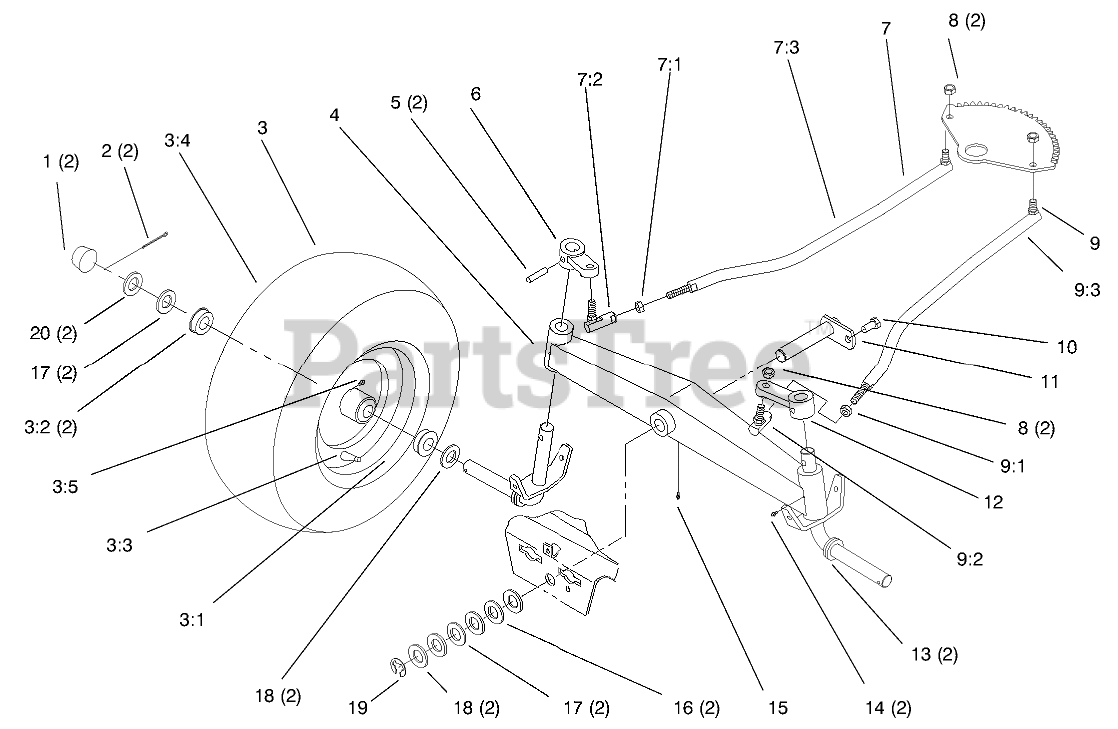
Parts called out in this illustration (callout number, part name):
1	CAP-HUB
2	PIN-COTTER
3	FRONT WHEEL ASM
3:1	Wheel ASM
3:2	BEARING-WHEEL
3:3	VALVE
3:4	Tire (16 x 6.5-8) 2-Ply -2 Wheel Axel
3:5	ZERK-GREASE
4	AXLE-FRONT
6	Arm-Front Spindle
7	LINKAGE-STEERING, RH
7:1	Nut-Hex Jam
7:2	BALL-JOINT
7:3	Ball Link ASM
9	LINKAGE-STEERING, LH
9:1	Nut-Hex Jam
9:2	BALL-JOINT
9:3	Ball Link ASM
10	SCREW-HWH, TAPTITE
11	PIN-AXLE
12	Arm-Front Spindle
13	SPINDLE
14	FITTING-GREASE
15	FITTING-LUBE, 45 DEG
16	Washer
17	WASHER
18	WASHER-SHIM
19	E-RING
20	WASHER-PLAIN
